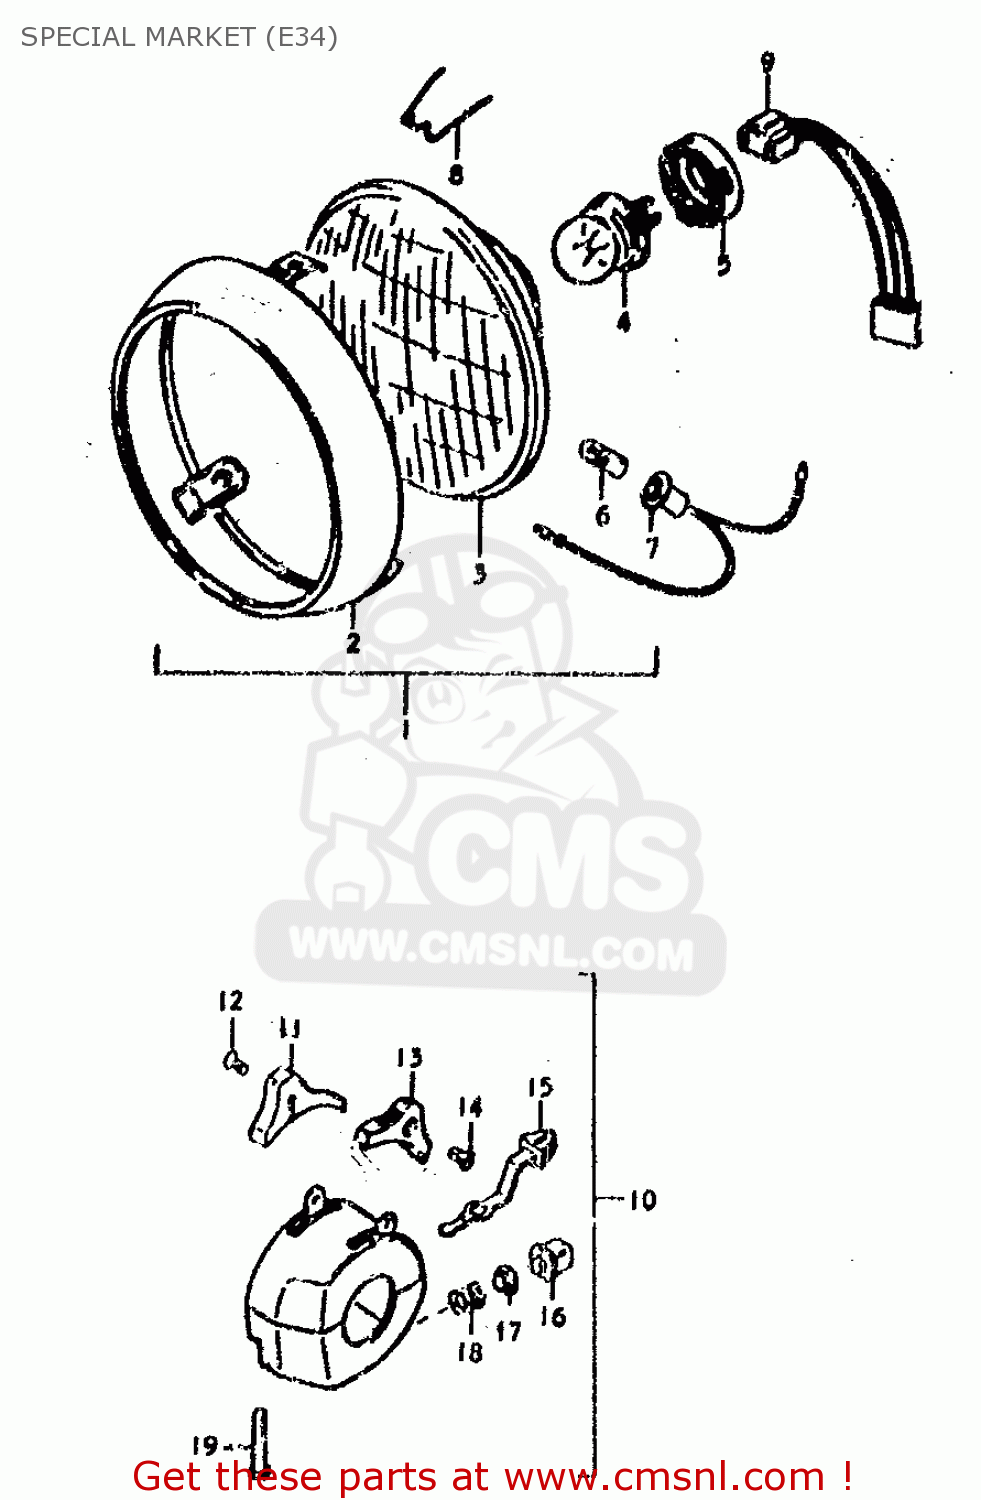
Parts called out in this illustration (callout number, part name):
1	HEADLAMP ASSY
2	RIM
3	UNIT
4	BULB(12V45/40W)
5	SETTER,BULB
6	BULB(12V4W)
7	SOCKET
8	SPRING,HEAD LA
9	LEAD WIRE,HEADLAMP
10	SWITCH ASSY,HANDLE LH
11	KNOB,LIGHTING SWITCH
12	SCREW
13	KNOB,DIMMER SWITCH
14	SCREW
15	KNOB,TURNSIGNAL
16	BUTTON,HORN
17	CONTACT
18	SPRING
19	SCREW
